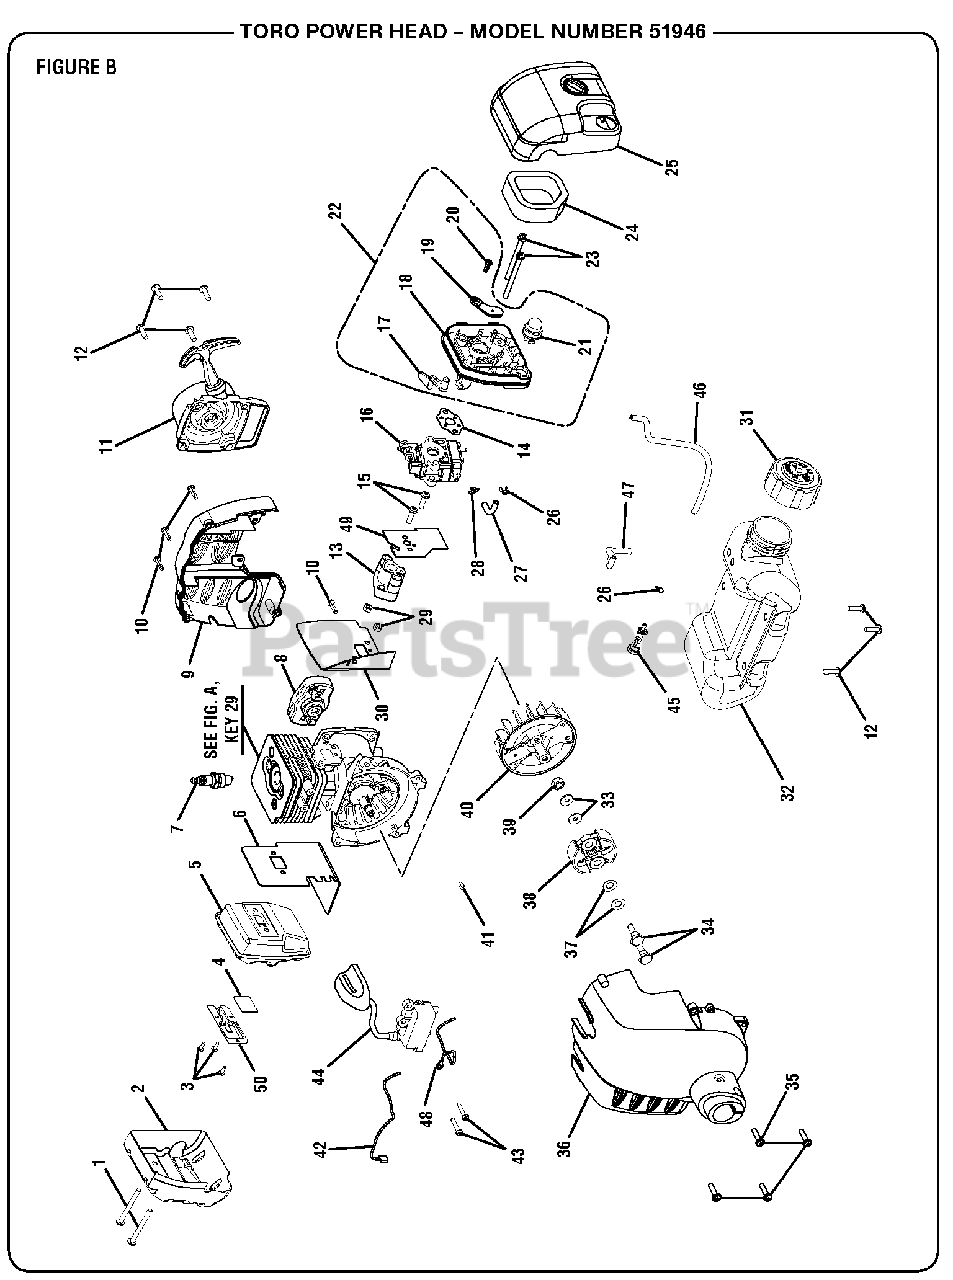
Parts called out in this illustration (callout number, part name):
1	Screw (M5 x 50 mm, Torx Slotted Recessed Pan Hd)
2	Heat Shield
3	Screw (6-20 x 1/4 in, Pan Hd)
4	Screen
5	Muffler Assembly
6	Muffler Gasket
7	Spark Plug (RCJ4Y)
8	Starter Cup
9	Rear Engine Housing
10	Screw (M4 x 16 mm, Torx Recessed Pan Hd)
11	Starter Recoil Assembly
12	Screw (m5 x 16 mm, Torx Slotted)
13	Heat Dam Insulator
14	Carburetor Gasket
15	Screw (M5 x 31 mm, Torx Slotted Recessed Pan Hd)
16	Carburetor Assembly
17	Choke Lever
18	Carburetor Plate
19	Choke Plate
20	Screw (M4 x 12 mm, Slotted Recessed Pan Hd)
21	Primer Assembly
22	Filter Housing Assembly
23	Screw (M5 x 60 mm, Slotted Recessed Pan Hd Machine)
24	Air Filter (Element)
25	Cover Assembly
26	Hose Clip
27	Fuel Line (45 mm)
28	Hose Clip
29	Hex Nut (M5 x 8 mm)
30	Insulator Gasket
31	Fuel Cap Assembly
32	Fuel Tank and Cap Assembly
33	Washer
34	Clutch Screw
35	Screw (M5 x 20 mm, Torx Slotted Recessed Pan Hd)
36	Front Housing Assembly
37	Curved Washer
38	Clutch Assembly
39	Rotor Nut
41	Woodruff Key (10 mm x 3 mm)
42	Lead Wire (Black)
43	Screw (M4 x 22 mm, Torx Slotted Recessed Pan Hd)
44	Coil Boot Assembly
45	Fuel Filter
46	Fuel Line (150 mm) [LP1500]
47	Fuel Line (118 mm)
48	Lead Wire (Red)
50	Trimmer Outlet
